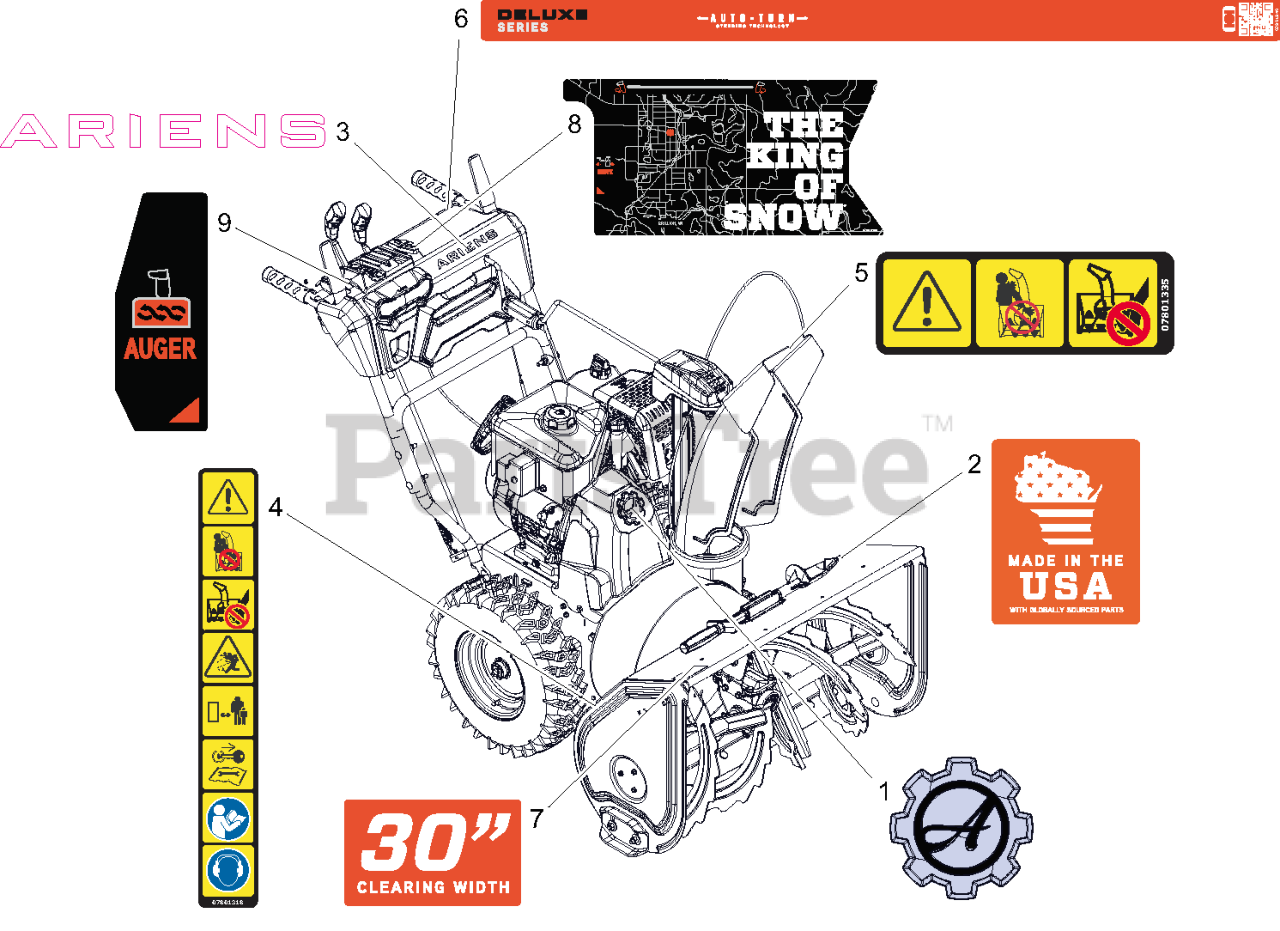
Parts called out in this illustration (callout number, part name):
1	DECAL, ARIENS - GEAR BADGE
2	DECAL- MADE IN USA
3	DECAL- ARIENS - 7.46"
4	DECAL- SAFETY - DANGER
5	DECAL- DANGER
6	DECAL- DASH - DLX
7	DECAL- CLEARING - 30
8	DECAL-CONTROL-LG CHUTE ROTATE
9	DECAL- CONTROL - AUGER
